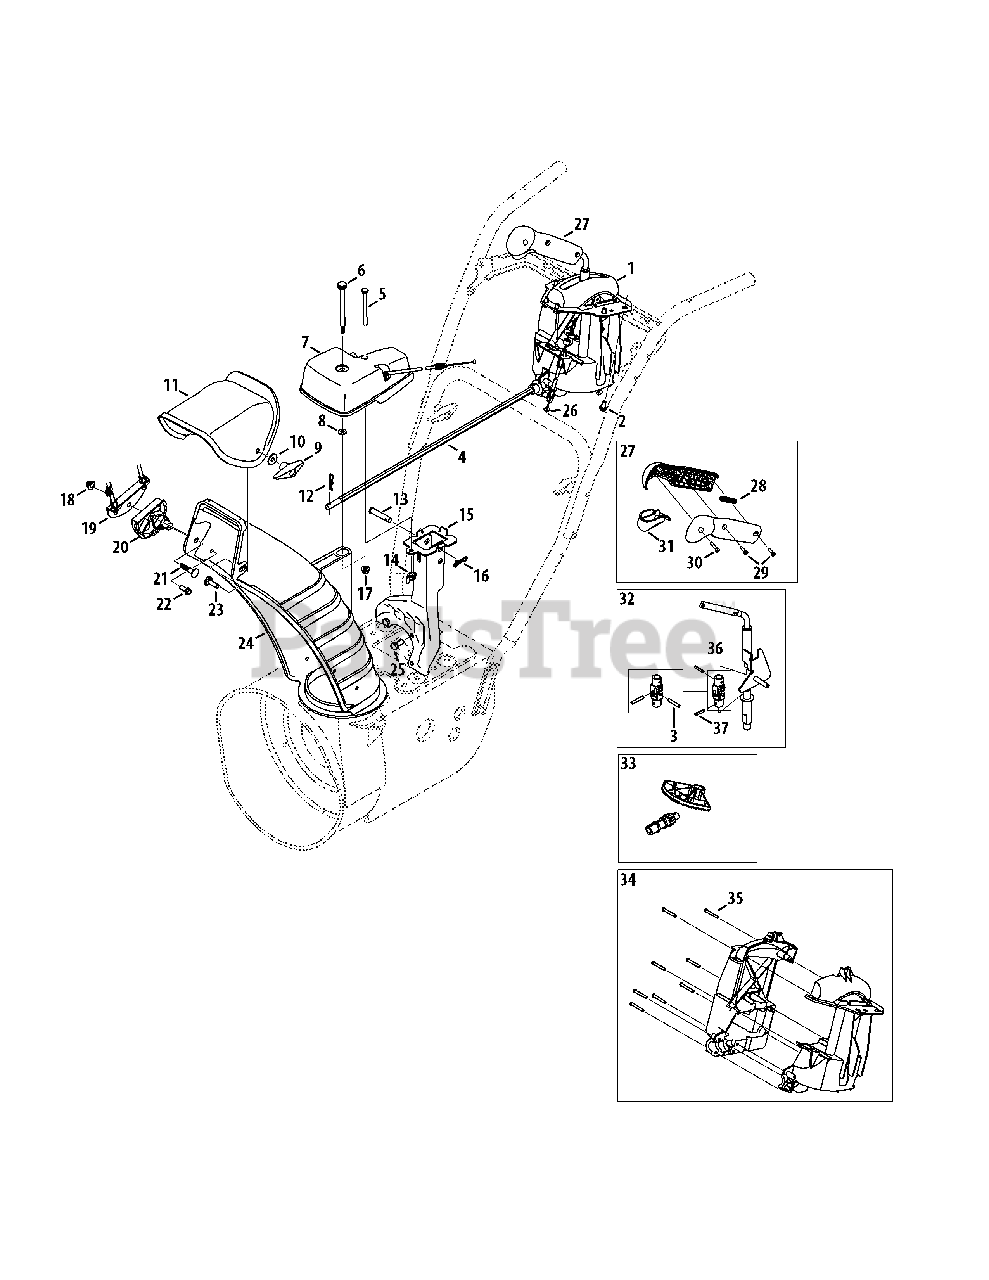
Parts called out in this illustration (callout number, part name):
1	4-Way Chute Control™ Assembly
2	Hi-Lo Screw, 1/4-15 x 0.5
3	Roll Pin
4	Chute Rod
5	Hex Screw, 1/4-20 x 3.00
6	Flange Shoulder Screw
7	4-Way Chute Gearbox Assembly
8	Flat Washer, .25 x .630 x .0515
9	Wing Knob
10	Flat Washer, .349 x .879 x .063
11	Upper Chute
12	Cotter Pin
13	Clevis Pin
14	Wing Nut, 1/4-20
15	Chute Support Bracket
16	Bow Tie Cotter Pin
17	Flange Lock Nut, 1/4-20
18	Flange Lock Nut, 5/16-18
19	Cable Bracket
20	Chute Tilt Cable Guide
21	Carriage Bolt, 5/16-18 x 1.50
22	Hi-Lo Screw, 1/4-15 x .75
23	Carriage Bolt, 5/16-18 x 1.0
24	Lower Chute
25	Hex Screw, 5/16-24 x .750
26	4-Way Cable
27	Handle Assembly
28	Handle Plunger
29	Screw, Mach., #8-32 x .750
30	Screw, #8 x 1.00
31	Handle Lever
32	Shift Assembly
33	Gear Set Assembly
34	Handle Housing Assembly
35	Screw, #8-18 x 1.250
36	Joint Block Assembly
